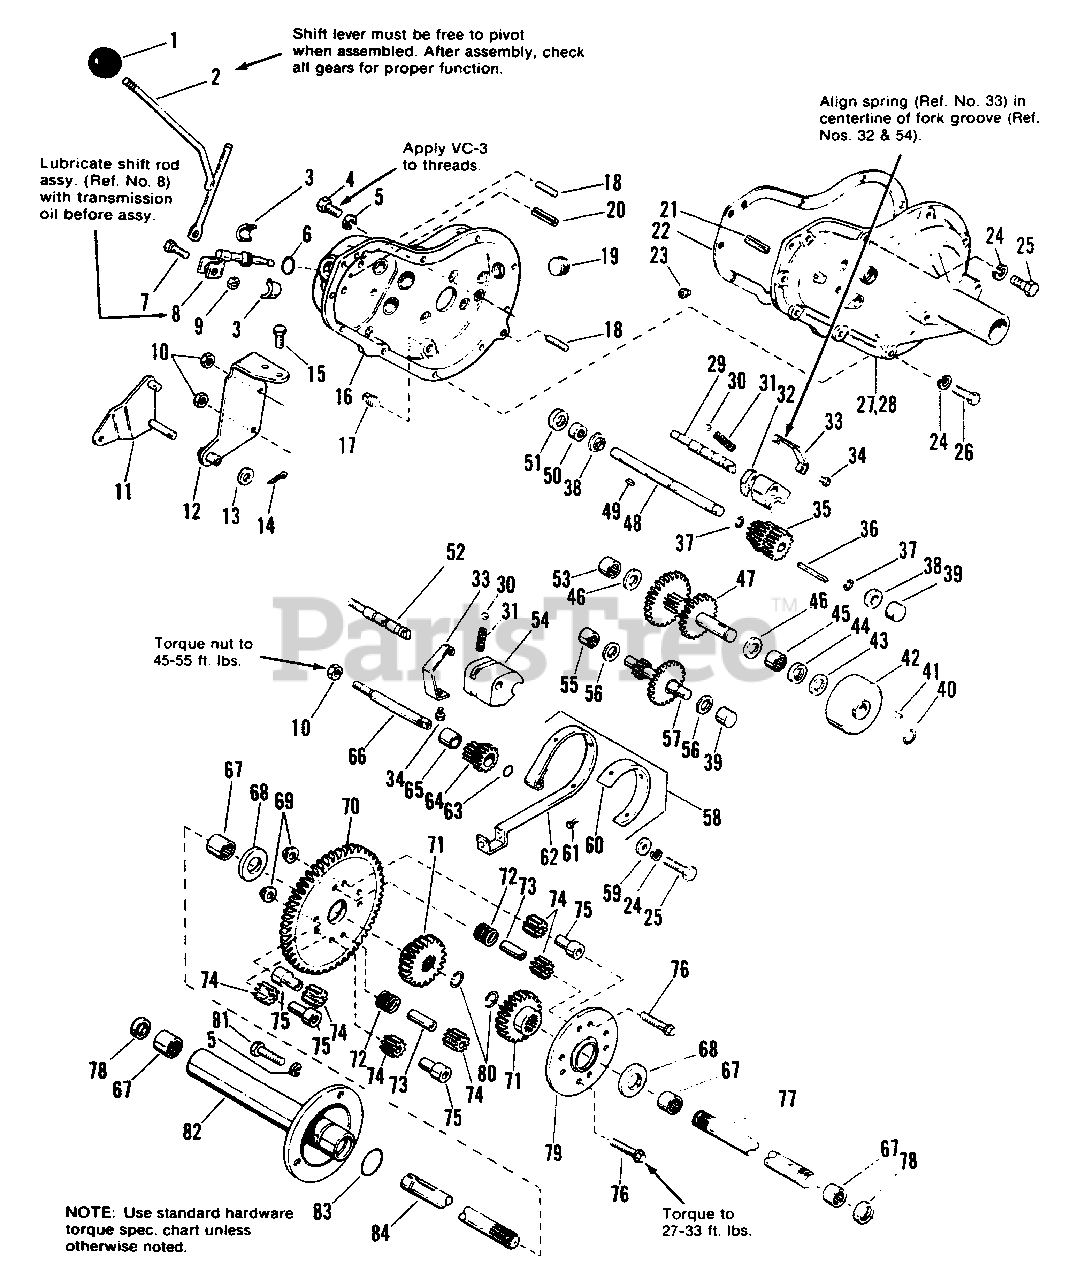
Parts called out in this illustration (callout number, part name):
2	ROD ASSY., Shift
4	CAPSCREW, Hex, 3/8-16 x 5/8
5	LOCKWASHER, 3/8
7	CAPSCREW, Hex, 1/4-20 x 1
8	ROD ASSY., Pivot
9	LOCKNUT, Hex, 1/4-20
10	LOCKNUT, Hex, Flange, 7/16-14
11	BRACKET ASSY., Pulley
12	SUPPORT ASSY., Transmission
13	WASHER, Plain, 3/8
14	PIN, Cotter, 3/32 x 3/4
15	CAPSCREW, Hex, 5/16-18 x 5/8
16	CASE ASSY., Gear
17	PLUG, Pipe, 3/8
18	PIN, Spring, 3/8 Dia. x 1
19	PLUG Pipe, 3/4
20	PIN ASSY., Roll
21	PIN ASSY., Roll
24	LOCKWASHER, 5/16
25	CAPSCREW, Hex, 5/16-18 x 1-1/2
26	CAPSCREW, Hex, 5/16-18 x 1-1/4
27	COVER ASSY., Gear Case
28	COVER, Gear Case
29	SHAFT, Shift, 2nd & 3rd
30	BALL, Shift Lock
32	FORK, Shift, 2nd & 3rd
34	CAPSCREW, Hex Washer Hd., 5/16-18 x 5/16
35	PINION ASSY., Drive
37	RING, Retaining
39	BEARING, Roller
40	RING, Snap
41	KEY, Woodruff, 3/16 x 5/8
42	DRUM ASSY., Brake
43	WASHER, Plain, 25/32
47	PINION SHAFT & GEAR CLUSTER ASSY.
48	SHAFT, Input
49	KEY, 3/16 x 3/4
52	SHAFT, Shift, 1st & Rev.
54	FORK, Shift, 1st & Rev.
57	PINION SHAFT & GEAR ASSY., 1st
58	BAND ASSY., Brake
59	WASHER, Plain, 5/16
60	LINING, Brake
64	PINION ASSY., 1st & Rev.
66	SHAFT, 1st & Rev. Pinion
67	BEARING, Roller
69	LOCKNUT, Flange, 3/8-16
70	GEAR, Drive
71	GEAR, Differential
73	SPACER, Pinion Diff
74	PINION, Diff.
75	STUD, Diff.
76	SCREW, Hex, Flange, 3/8-16 x 2-1/2
77	SHAFT, Axle, R.H.
79	PLATE, Diff.
81	CAPSCREW, 3/8-16 x 7/8
82	HOUSING & BEARING ASSY, Axle (Includes Ref. No. 67)
84	SHAFT, Axle, L.H.
